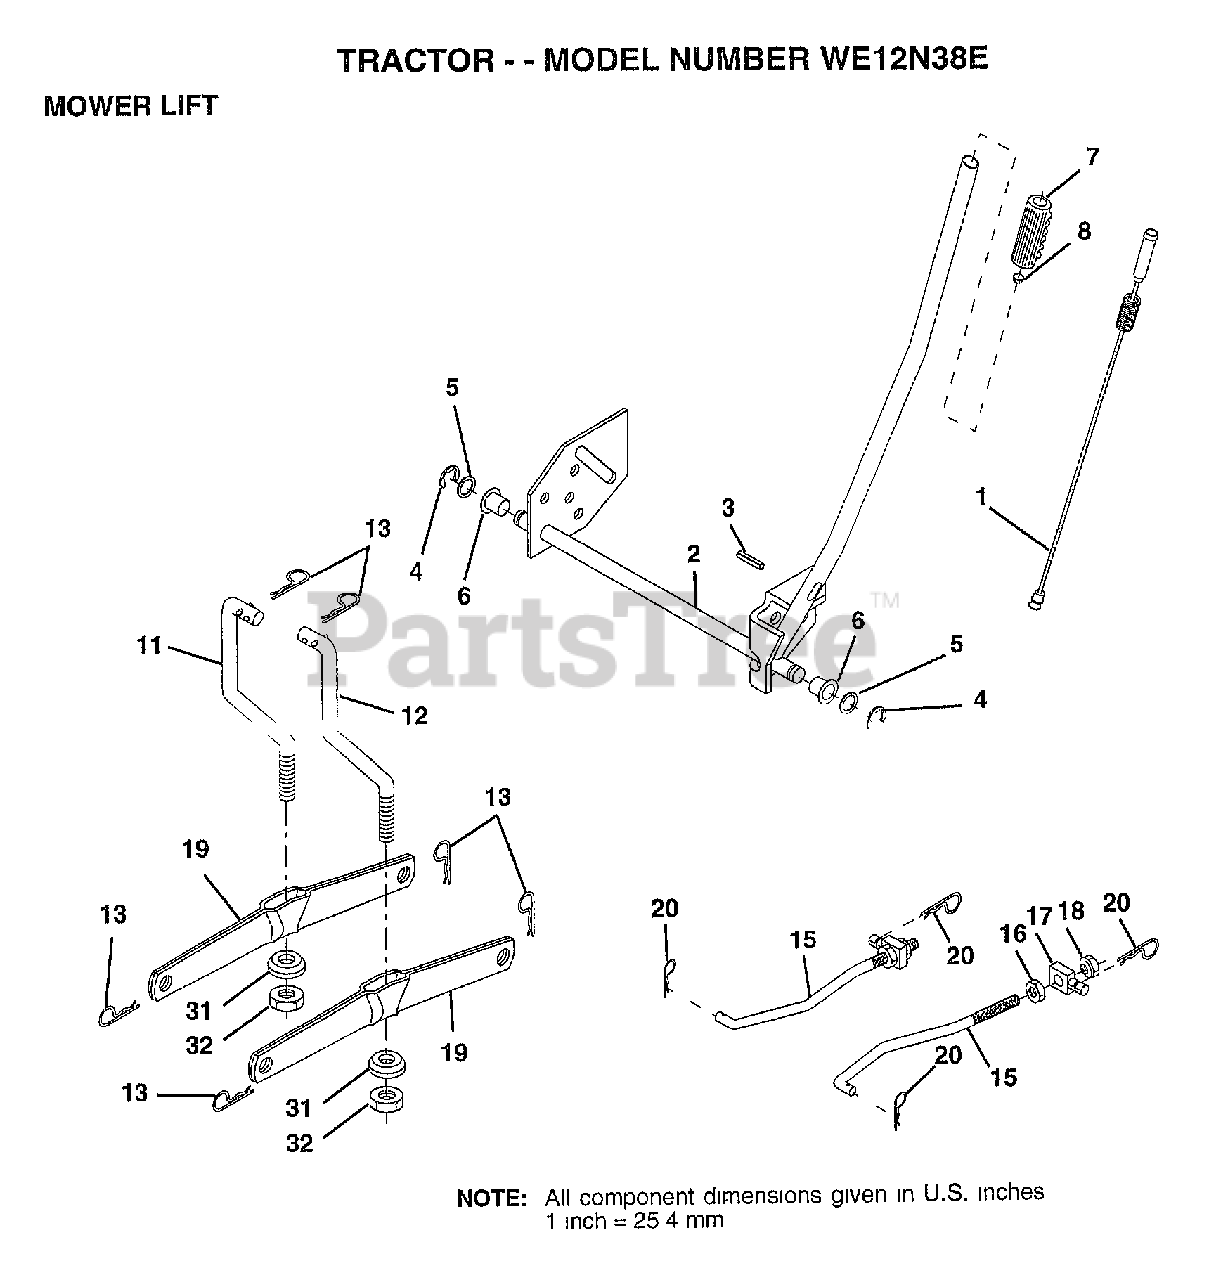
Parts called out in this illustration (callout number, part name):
1	WIRE ASM W.SPRING
2	SHAFT ASM.LIFT
3	PIN-GROOVE LT
5	WASHER
6	NYLON BEARING
7	GRIP
15	LINK.FRONT
16	NUT
17	TRUNION
18	NUT.LK.W/WSH.1/2.
19	ARM SUSP REAR
20	RETAINER.SPRING
31	BEARING PVT LH
32	NUT.CROWNLOCK.3/8
